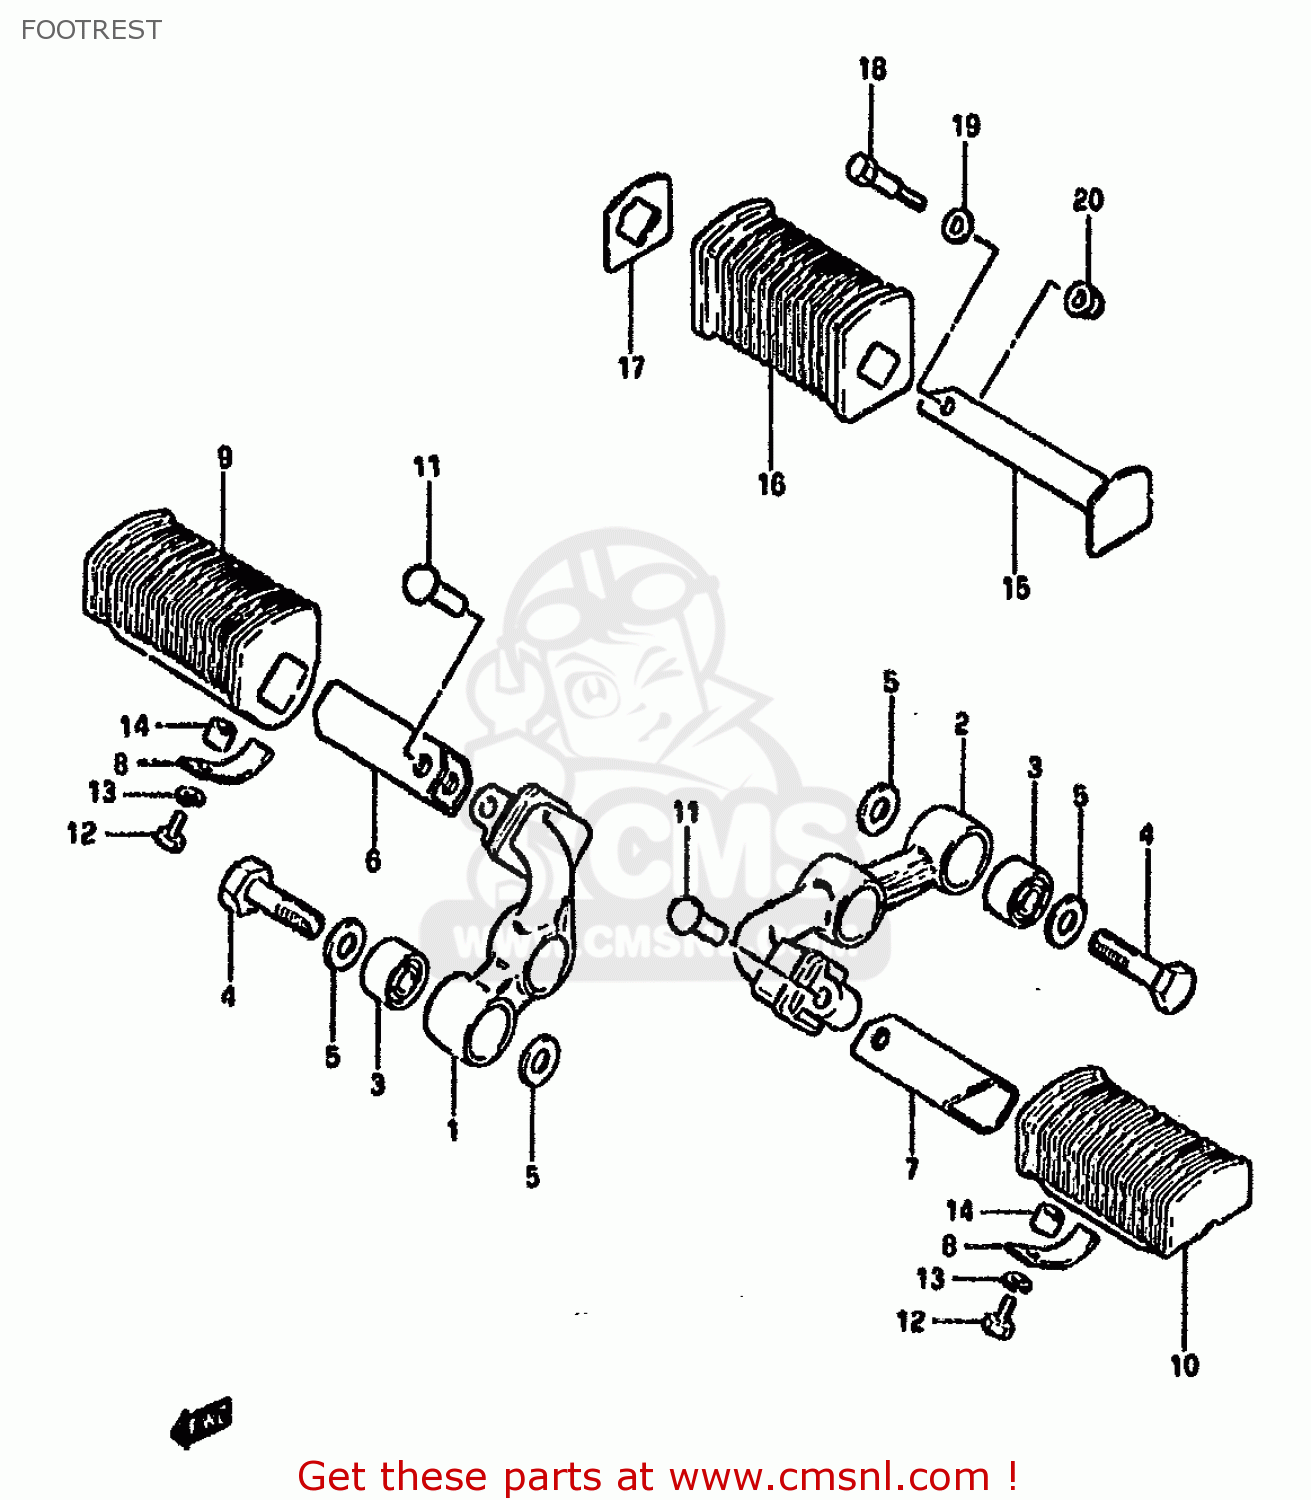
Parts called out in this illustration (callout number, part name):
1	BAR, FOOTREST RH
2	BAR, FOOTREST LH
3	BUSH
4	BOLT
5	WASHER
6	HOLDER, COVER RH
7	HOLDER, COVER LH
8	PLATE, FOOTREST STOPPER
9	RUBBER,FR FOOTREST,R
10	RUBBER,FR FOOTREST,L
11	RIVET
12	BOLT, UPPER
13	LOCK WASHER
14	SPACER(6.5X10.5X6.5)
15	BAR, RH
16	RUBBER,PILLION FOOTREST
17	WASHER,PILLION FOOTREST RUBBER
18	BOLT(6X40)
19	WASHER
20	NUT
